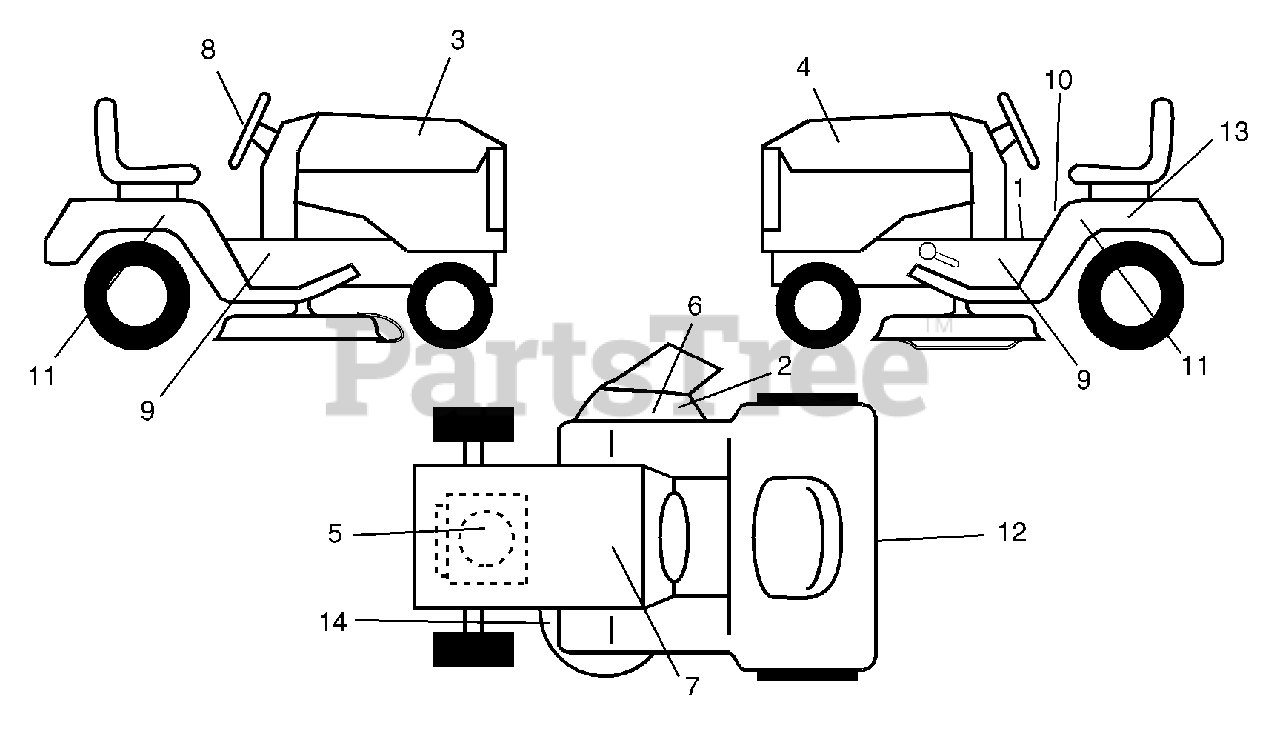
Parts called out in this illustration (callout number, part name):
1	Decal Oper
2	Decal Footrest
3	Decal Hood RH Statesman
3	Decal Hood RH Agway
4	Decal Hood LH Statesman
4	Decal Hood LH Agway
5	Decal HP Engine
6	Decal Deck "B" 42"
7	Decal Repl. Parts
8	Decal Steering Wheel Statesman
8	Decal Steering Wheel Agway
9	Decal 18/42 Statesman
9	Decal 18/42 Agway
10	Decal Fender Danger E/F
11	Decal "Automatic"
12	Decal Statesman
12	Decal Agway
13	Decal Battery
14	Decal V-Belt Schematic
